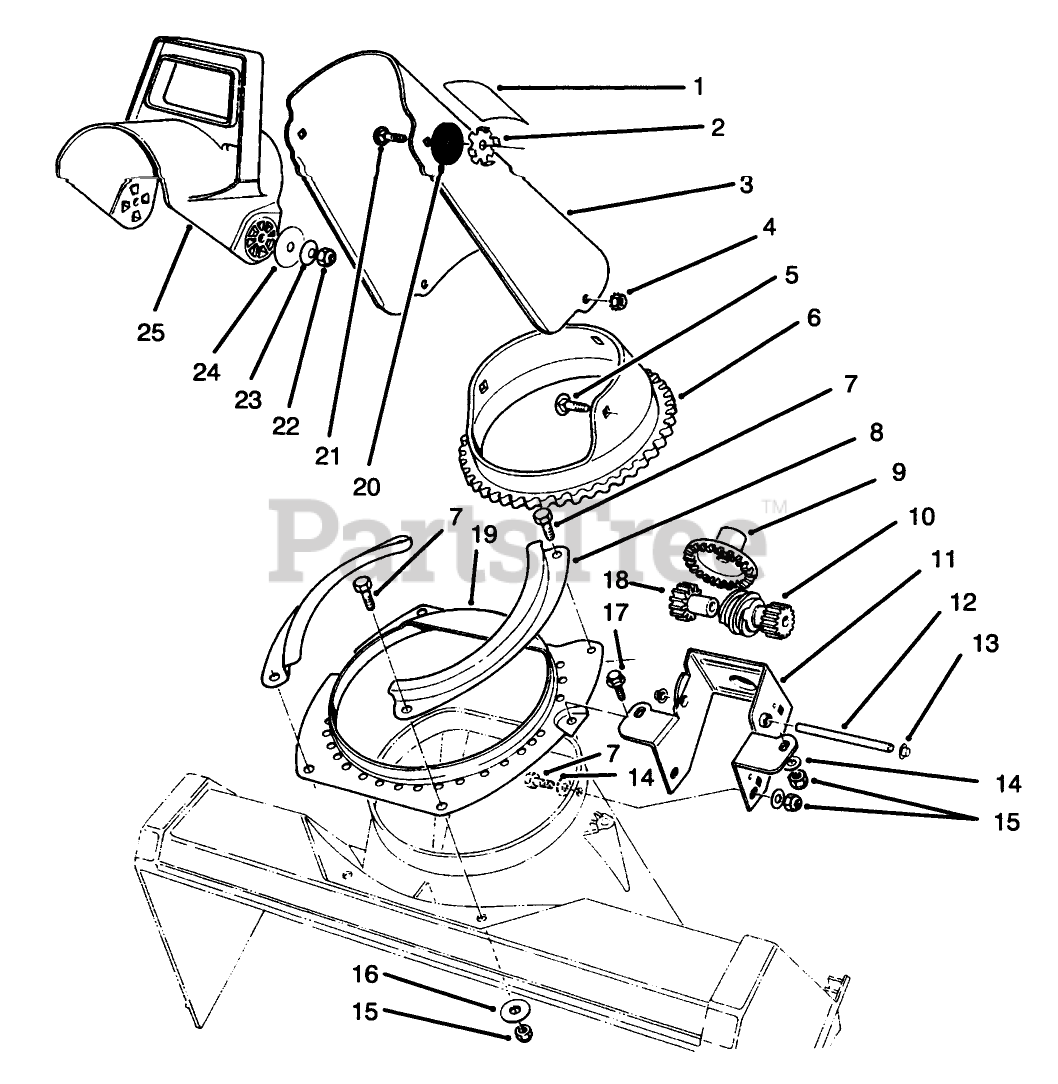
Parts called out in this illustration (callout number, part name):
2	PLATE-FRICTION
4	NUT-KEPS
5	SCREW-CARR
6	RING-GEAR, CHUTE
7	SCREW-HH
9	GEAR-FACE
12	SHAFT-GEAR, WORM
13	NUT-PUSH
14	WASHER-FLAT
15	NUT-LOCK, NI
16	WASHER-FLAT
17	SCREW-PLASTITE
18	GEAR-SPUR, SPACER
20	WASHER-RUBBER
21	SCREW-CARR
22	NUT-LOCK, NI
23	WASHER-BELLEVILLE
24	WASHER-FLAT
25	CHUTE-DEFLECTOR
